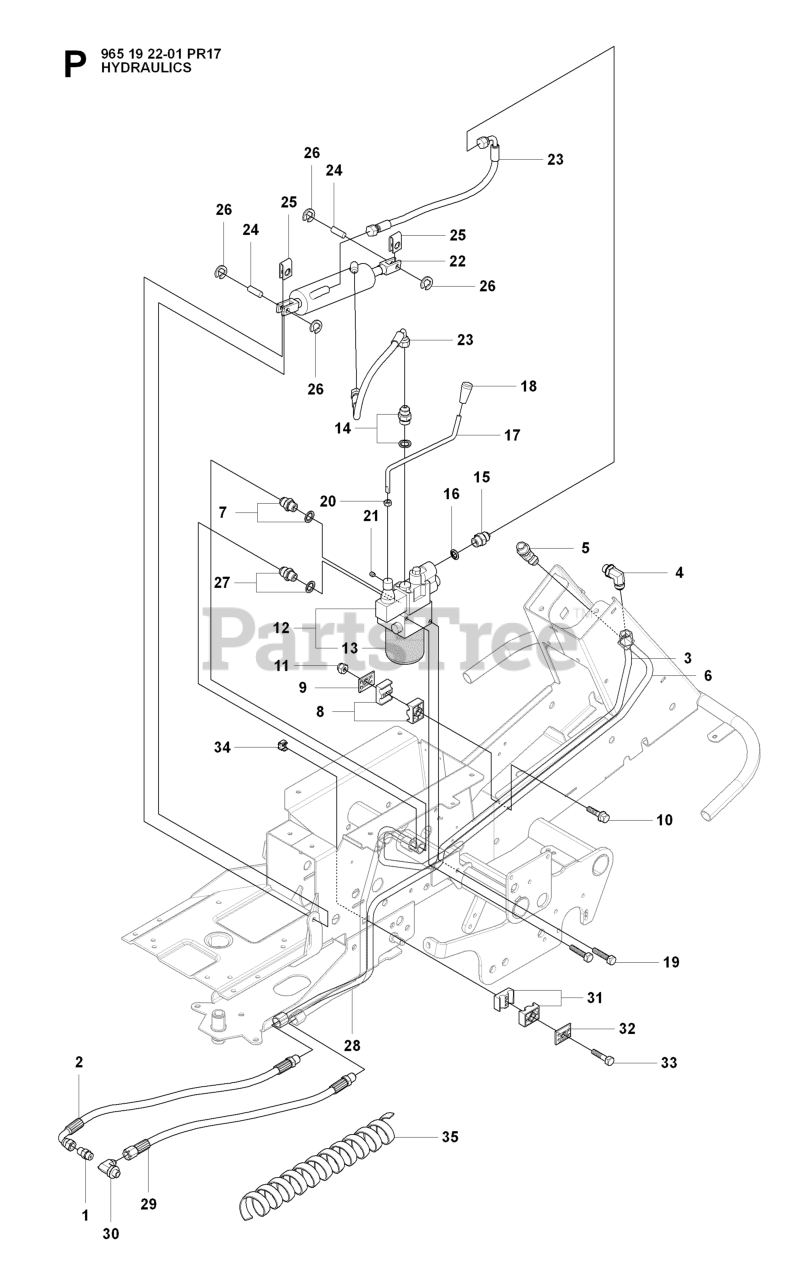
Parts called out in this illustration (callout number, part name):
8	PIPE CLAMP
11	LOCKNUT M6
13	FILTER
19	REPL BY 725 24 49-51
20	NUT
26	RETAINING RING SGA 10
31	PIPE CLAMP
